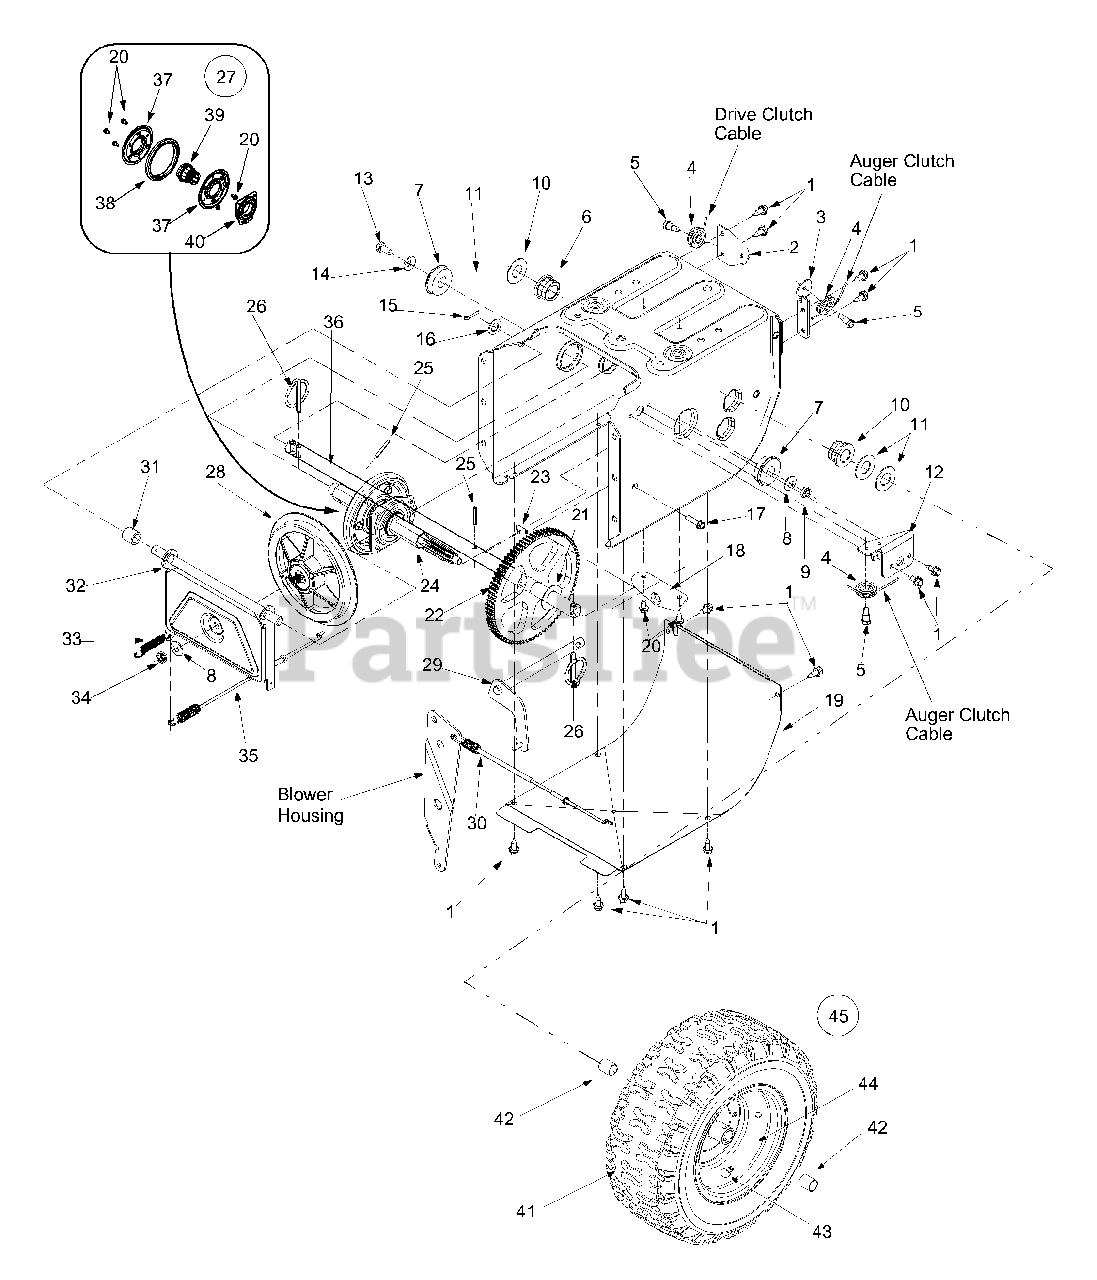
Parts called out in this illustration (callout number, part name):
1	Hex Screw
5	Hex Screw 1/4-28
8	Bell Washer
9	Lock Jam Nut
10	Hex Flange Bearing
11	Flat Washer
14	Bell Washer .340 ID x .872 OD
15	Cotter Pin
16	Flat Washer .536 ID x .930 OD
17	Hex Washer Screw 1/4-20
21	Flat Washer .760 ID x .50 OD
24	7-Tooth Shaft
25	Roll Pin
26	Clik Pin
27	Friction Wheel Assembly
28	Friction Disc Wheel
29	Wheel Shift Rod Assembly
30	Drive Cable
31	Spacer
34	Jam Nut, 3/8-24
35	Drive Cable
39	7-Tooth Shaft
40	Friction Wheel Bearing
41	Tire Only, 16 x 6.5 x 8
42	Sleeve Bearing
43	Air Valve
